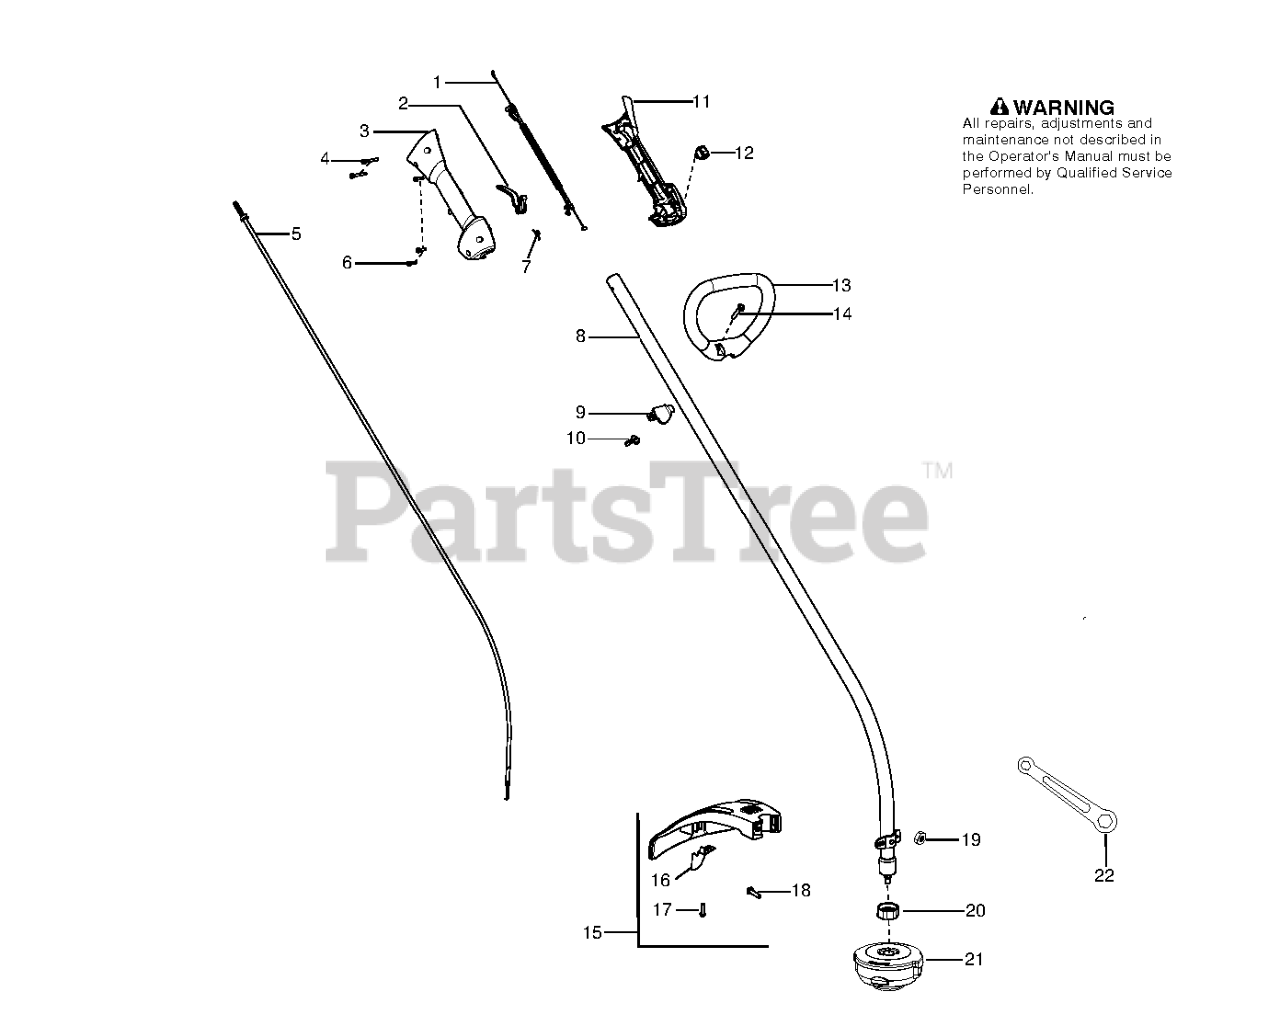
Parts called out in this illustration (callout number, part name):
1	ASSY-CABLE WIRE HARNESS
2	TRIGGER THROTTLE
3	HOUSING-THROTTLE (RH)
5	FLEX SHAFT 52"
6	SCREW M4 X 1.75 PT 16MM
7	SPRING TRIGGER
8	KIT-DRIVESHAFT
9	CLAMP ASSIST HANDLE
10	WINGNUT, TYPE 2
11	HSG THROTTLE LH
12	KIT SWITCH
13	HANDLE ASSIST
14	BOLT, TYPE 2
15	SHIELD ASSY
16	KIT - LIMITER - LINE
18	BOLT, TYPE 2
21	Assy-T25 Cutting Head
